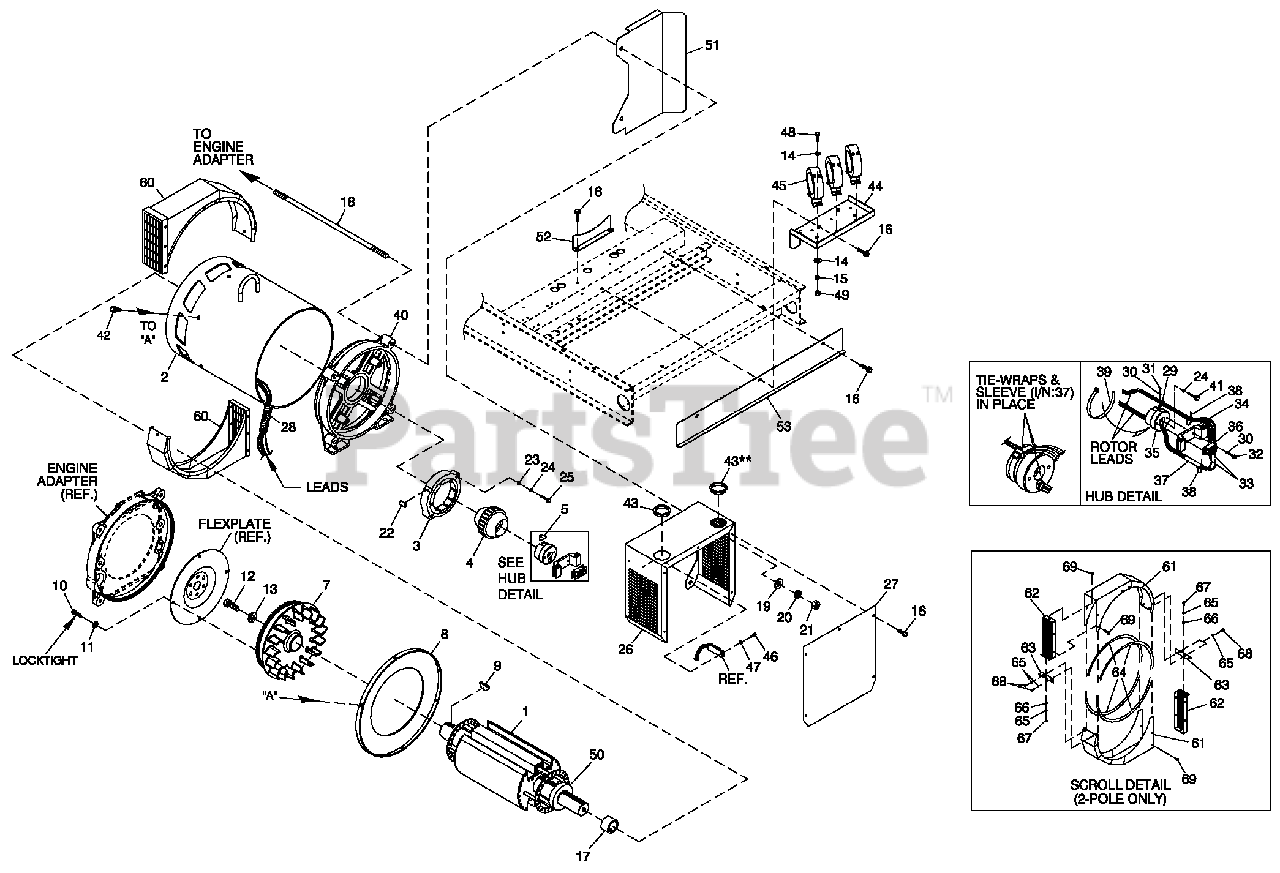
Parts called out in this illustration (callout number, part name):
1	ASSY ROTOR 2390 80KB3 CPL
2	ASSY STATOR 80KW 1PH 2P BRSHLS
3	EXITER FIELD 2" LG SPD CONN
4	ASSY EXCITER 2.0" STACK 2P
5	KEY SQ 3/8 X 3-1/4 STEEL
7	ASSY FLYWHEEL CPL
8	RING PRESSURE 390 STATOR CAN
9	KEY WOODRUFF #E
10	SCREW HHC M10-1.5 X 25 C10.9
11	WASHER LOCK M10
12	SCREW HHC M16-2.0 X 45 G8.8
13	SPACER .69 X 2.75 X .37 ST/ZNC
14	WASHER FLAT 1/4-M6 ZINC
15	WASHER LOCK M6-1/4
16	SCREW THF M6-1 X 16 N WA Z/JS
17	COLLAR SLIP FIT 390 MM
18	STUD M14-2.0 X 760 G5 ZINC
19	WASHER FLAT M14
20	WASHER LOCK M14
21	NUT HEX M14-2.0 G8 YEL CHR
22	PIN DOWEL 1/2 X 1-1/4
23	WASHER FLAT M12
24	WASHER LOCK M12
25	SCREW HHC M12-1.75 X 80 G10.9
26	SHIELD ALT EXCITER 390
27	COVER EXCITER SHIELD
28	CONDUIT FLEX 1.25" ID
29	CLAMP VINYL .312 X .203 Z
30	WASHER SHAKEPROOF INT #8
31	SCREW HHM #8-32 X 3/8
32	SCREW HHM #8-32 X 7/8
33	LUG RT-ANG #10/10-12
34	BRIDGE SUPPORT DIODE 15"
35	CAP END ROTOR 390MM
36	ASSY BRIDGE RECTIFIER
37	SLEEVING UL #0 .330 ID (3" LG)
38	TIE WRAP UL 3.9" X .10" BLK
39	TIE WRAP UL 17.7 X .35 BLK HT
40	REAR BEARING CARRIER CPL
41	SCREW HHC M12-1.75 X 60 G10.9
42	SCREW 1/4-20 X 5/8" TAPTITE SS
43	BUSHING SNAP SB-2.5-31
44	MOUNT CT'S 5.4L 100KW
45	TRANSFORMER
46	SCREW PHTT #6-32 X 1/2 ZYC
47	WASHER LOCK #6
48	SCREW HHC M6-1.0 X 20 G8.8
49	NUT HEX M6 X 1.0 G8 YEL CHR
50	BEARING BALL 6212 SEALED
51	SHROUD UPPER ALTERNATOR EXCITR
52	SHROUD CENTER ALTERNATR EXCITR
53	SHROUD LOWER ALTERNATOR EXCITR
60	ASSY SCROLL 390 X 60MM CPL
61	SHROUD ALT SHEET METAL CPL 2P
62	SCREEN, 390 SAE ALT 60MM WIDE
63	BRACKET SAE SCROLL TENSIONER
64	VINYL TRIM 1/8" GAP
65	WASHER, SPLIT 1/4"-M6
66	WASHER FLAT 1/4 ZINC
67	SCREW HHC M6-1.0 x 25 LONG
68	SCREW HHC M6-1.0 X 16 G8.8
69	SCREW SWAGE 1/4-20 X 1/2 Z/YC
